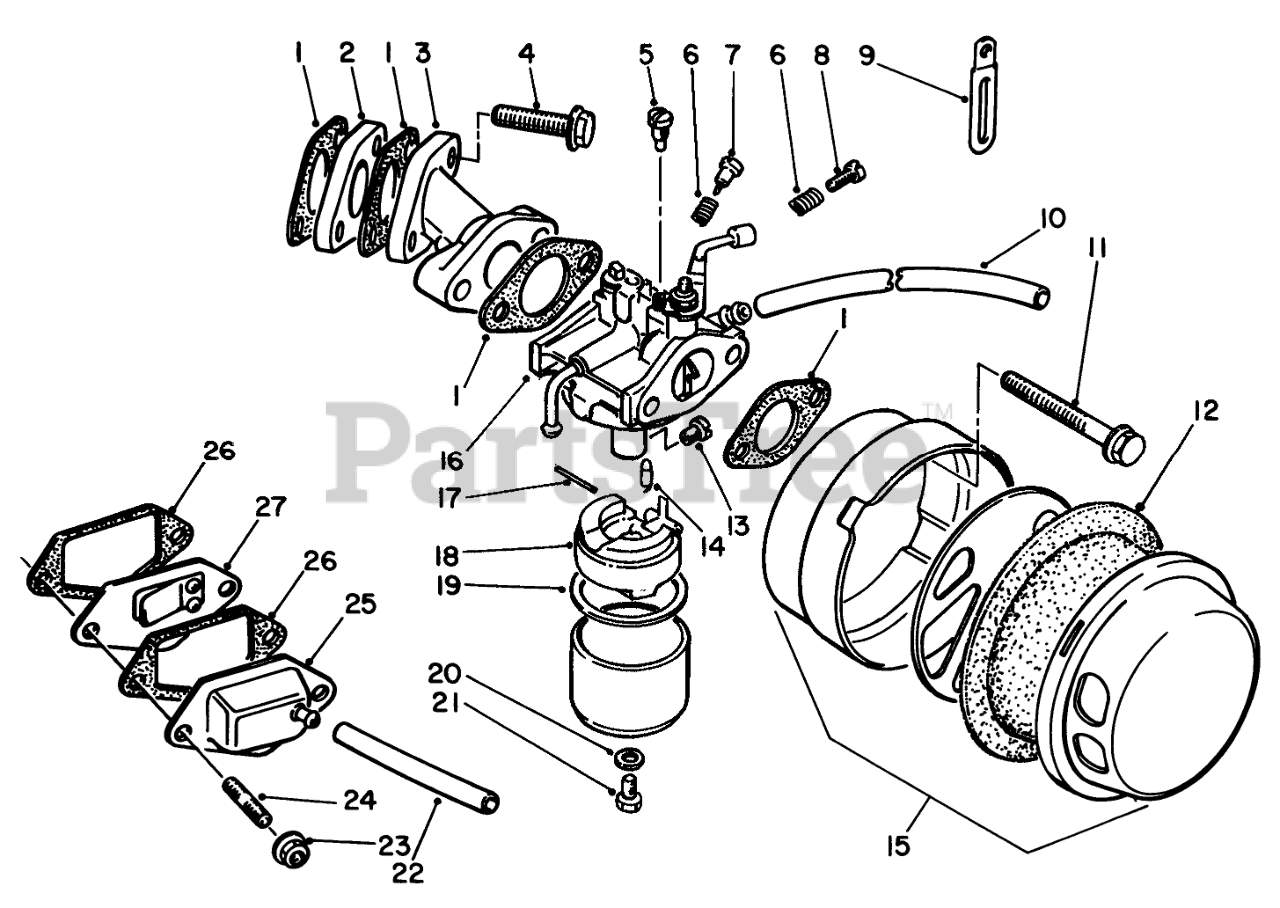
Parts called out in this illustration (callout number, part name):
1	GASKET
2	Insulator
5	Jet
6	SPRING
7	ADJUSTER
8	SCREW
9	CLAMP
10	Hose-Overflow
11	Screw-Hex Flange Hd.
12	FILTER FOAM
13	Jet-Main
14	NEEDLE ASSM.
15	Air Cleaner Assembly
16	Carburetor Assembly (Incl. Items #13, 14, .17-21)
17	Pin
18	FLOAT
19	GASKET
20	GASKET
21	Screw-Hex Hd.
24	Bolt-Stud
25	Cap-Breather
26	Gasket
27	REED VALVE
